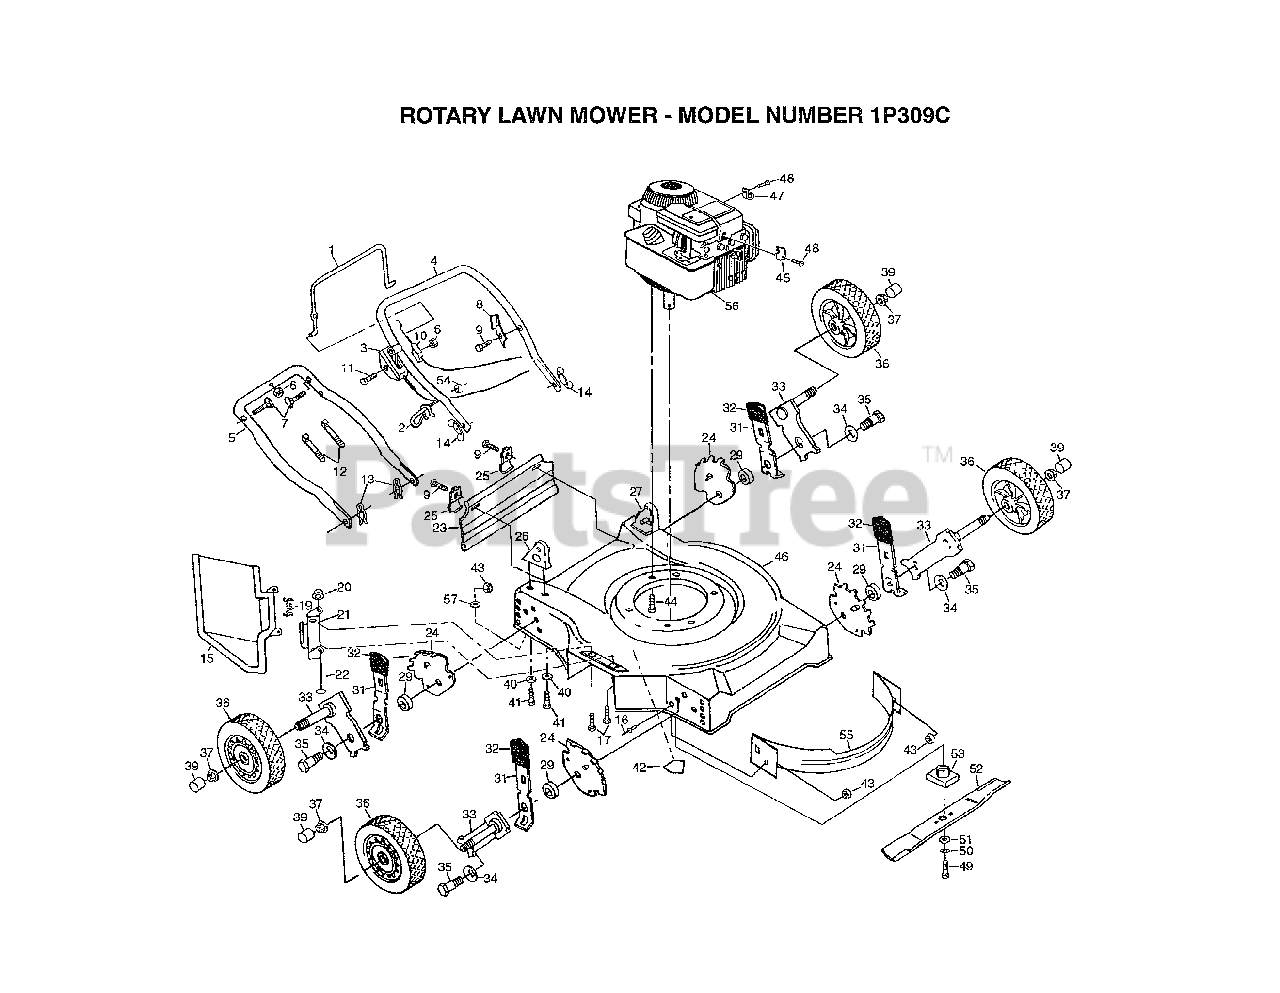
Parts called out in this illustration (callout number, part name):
1	CONTROL BAR PM
2	ROPE GUIDE
3	CONTROL THROTTLE
7	BOLT.HANDLE.LM
8	"BRKT,UPSTOP"
9	TAPPING SCREW
10	"CABLE,ENG ZONE CO"
11	SCREW.HXHD.WASH.
13	HAIRPIN COTTER
14	"NUT,WING PM"
15	"GRD,DISCHARGE"
16	BLIND RIVET
17	SCREW
19	"SPRING,TORSION"
20	PUSH ON SPEED NUT
21	"BRKT,HSG "
23	SKIRT.RD.20/22
24	BRACKET.ADJ.9POS.
25	"BRKT,DEFL PM"
29	SPACER.HEIGHT.ADJ
31	SPRING SELECTOR
32	KNOB PM
33	ARM.AXLE.ASM.BZP.
34	"WASHER, BELLEVIL."
35	BOLT SHLD 3/8-16
36	WHEEL&TIRE
37	HEX FLANGE LOCKNT
39	HUB CAP-PLASTIC
40	STEEL WASHER
41	SCREW
42	DECAL HYT
43	LOCKNUT PM
44	SCREW
45	CABLE CLAMP
46	"KIT.HSG.20""SDPUSH"
47	GUIDE CLIP PM
48	SCREW PM
49	SCREW
50	LOCKWASHER
51	"WASHER,HARDEN"
52	BLADE.20.MULCH.AY
53	BLADE ADAPTOR
54	NUT
